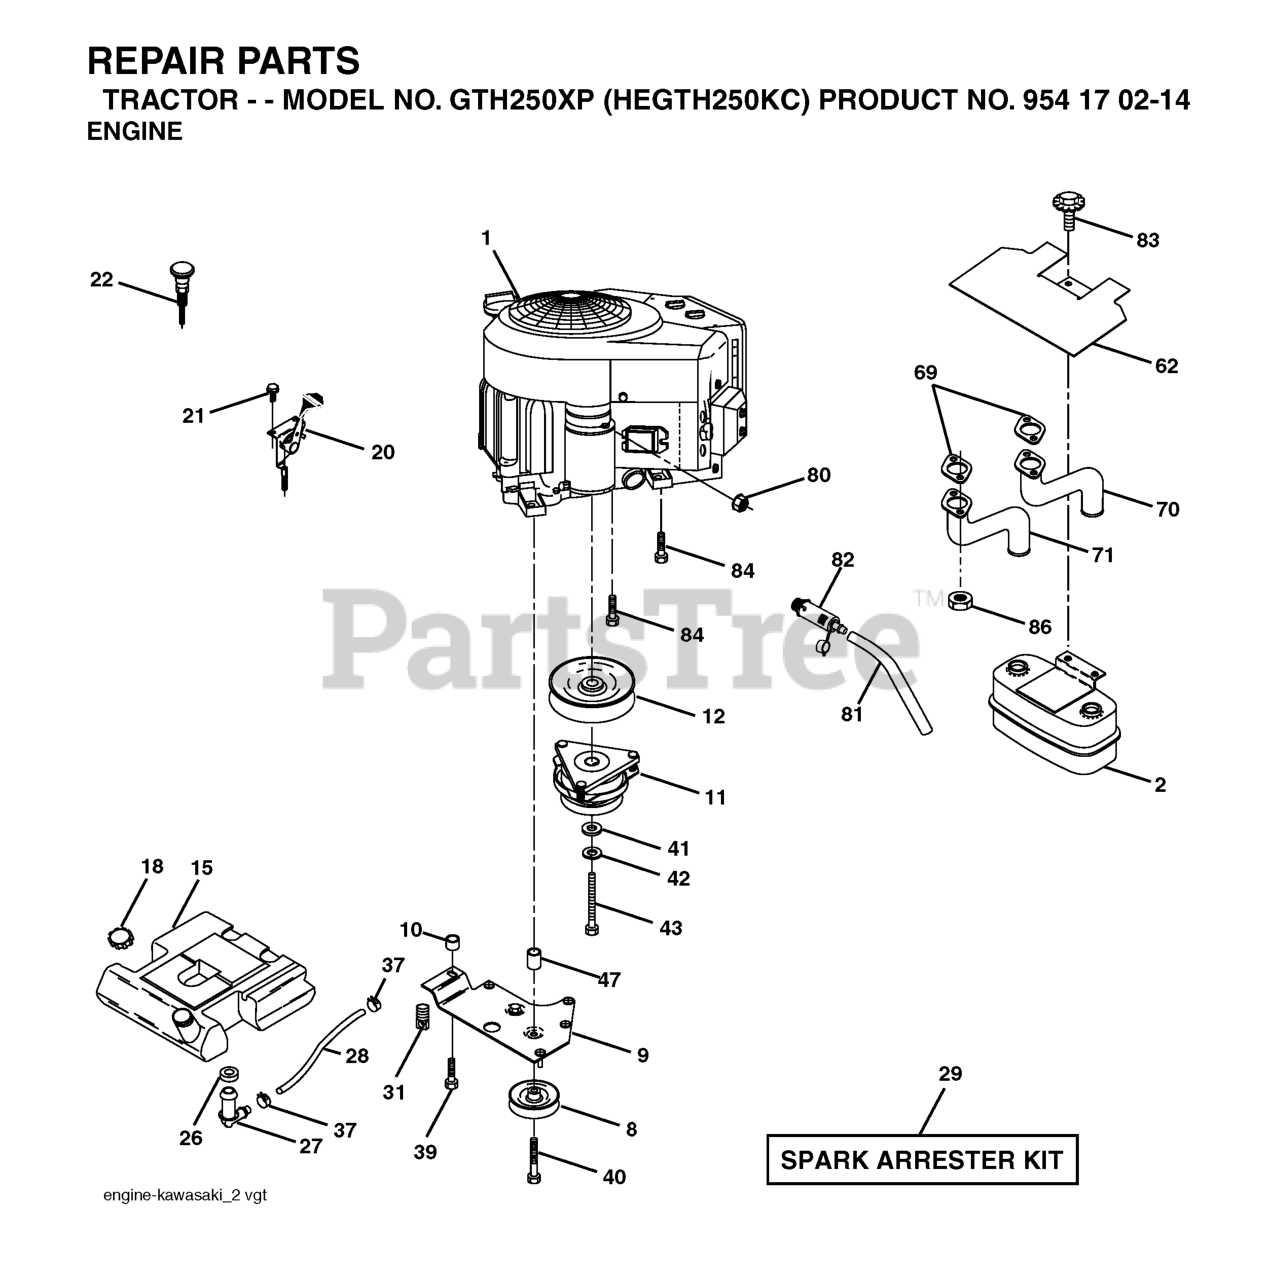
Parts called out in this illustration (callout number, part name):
1	RP SPRING, TRACTION IDLER
2	MUFFLER.TWIN.CYL.LOW.TONE
2	PULLEY.W/SPACER.2.25
4	BOLT.5/16-18X1-1/4 FULL.THREAD
6	STEEL WASHER
7	LOCKNUT 5/16-18
8	RP.IDLER GROOVED
8	PIN, IDLER PIVOT
9	KEEPER ASM BELT ENGINE
10	WASHER.LOCK.HVY.HLCL.SPR.5/16
11	CLUTCH MZ ZTR GT.48/54"1.125"
11	Screw 5/16-18 x 1/2 Hex, Self Tapping 5/16-18 x 1/2
12	PULLEY ENG VGT ELECT CLUTCH
12	ARM PAD ASSY
13	RETAINER CLIP PM
14	SPRING, BRAKE
15	TANK.FUEL.5.0 LEFT.FILL.YTGT
15	BELT.V.IMPELLER
16	BOLT 3/8-16X1-1/8
17	IDLER ARM
18	TANK CAP
18	HEX BOLT
19	RP BUSHING, IDLER PIVOT
20	CONTROL.THROTTLE.COBRA.42"BLK.
20	PULLEY.W/SPACER.2.75
21	SCREW
22	CHOKE CONTROL
22	SPACER.ENGINE.PULLEY
23	PULLEY,ENGINE TRACTION DRIVE
24	PULLEY, ENGINE IMPELLER DRIVE
25	Nut Keps 3/8 - 24 UNF
25	WASHER, FLAT 3/8
26	BUSHING OUTLET T
26	LOCKWASHER
27	STEM FUEL TANK
27	SCREW, HEX HD 3/8-24 X 1-3/8
28	FUEL LINE
28	BELT.GUIDE.RH
29	KIT.SPARK ARRESTOR 794945 B&S
29	COVER.ASM.BELT/STORAGE
30	COVER.STORAGE.SNOW
31	SCREW
32	BOLT.SHOULDER.3/X.25
33	BRACKET.SHIFTER.PLATE.BZP
34	CLEVIS PIN
35	ARM, AUGER CONTROL
36	NUT.HEX.FLANGE.1/4
37	HOSE CLAMP
37	PLATE.CLUTCH.BZP
38	LINK, SPEED CONTROL
39	SCREW TT 3/8-16X2-1/4 UNC
39	BRACKET.CLUTCH.PLATE.BZP
40	Screw TT 3/8-16 x 4 unc
41	RETAINER CLIP
42	LOCKWASHER
43	BOLT HEX 7/16-20 X 3.75 GR. 5
43	PLATE.SHIFTER.BZP
44	SCREW 3/8-16X1
45	BRACKET, IDLER PIVOT
46	PAN.BOTTOM.PLASTIC
47	SCREW, HEX HEAD, TAPPING
48	LOCKNUT 5/16-18
49	FRAME.WELD.PNT.003BGP
50	PLATE.REAR
51	SHAFT, AUGER CONTROL
52	THRUST WASHER
53	KEY.PUSH/PULL.B&S.283707
56	PLATE.ENGINE.MOUNT.PNT
57	WASHER EXT TOOTH LOCK 5/16
62	HEAT SHIELD
70	TUBE EXHAUST LH
71	TUBE.EXHAUST.KAWASAKI.RH
80	FLANGE NUT
81	TUBE, DRAIN OIL ASM.
82	PLUG DRAIN OIL EASY
83	BOLT.5/16-18UNCX3/4 W/SEMS.BLK
84	SCREW 3/8-16 X 1-1/2
86	NUT.HEX.FLANGE.TOPLOCK
